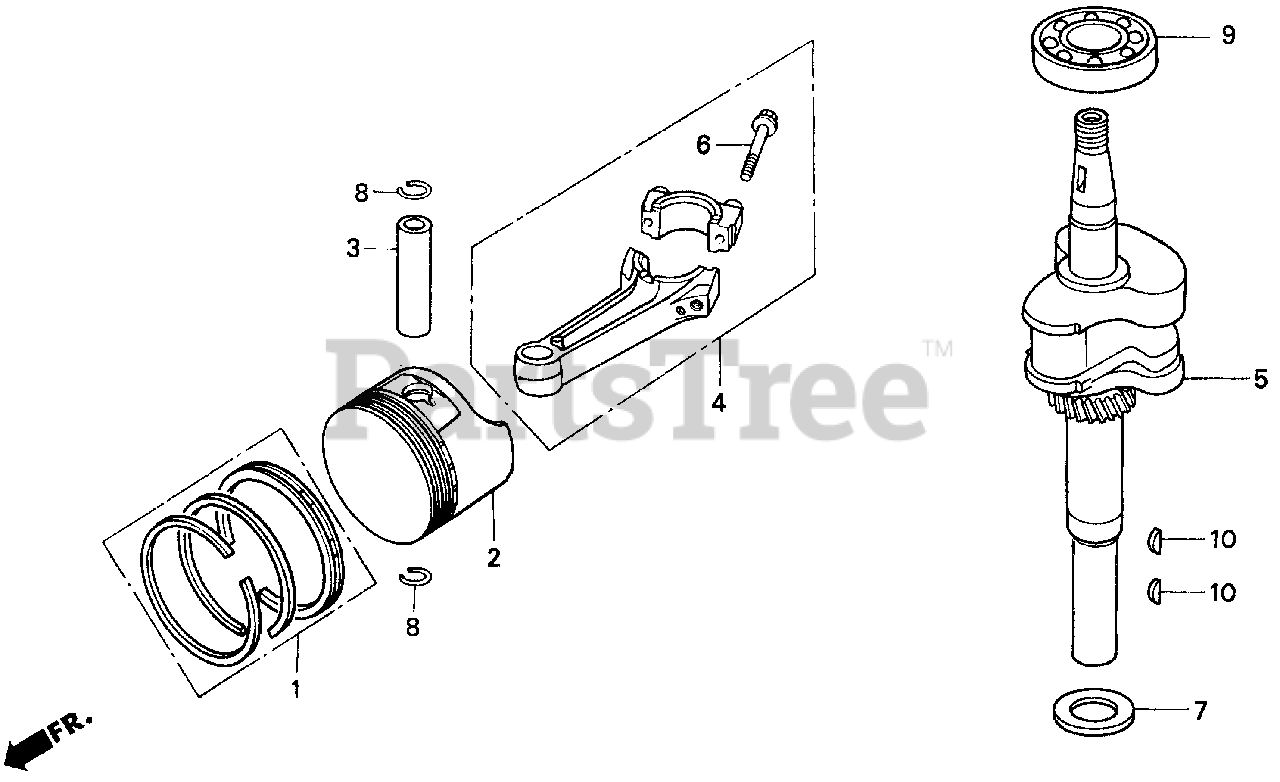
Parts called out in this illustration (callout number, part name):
1	RING SET, PISTON (STD)
1	RING SET, PISTON (OS 0.25)
1	RING SET, PISTON (OS 0.50)
1	RING SET, PISTON (0.75)
2	PISTON (STD)
2	PISTON (OS 0.25)
2	PISTON (OS 0.50)
2	PISTON (0.75)
3	PIN, PISTON
4	ROD ASSY., CONNECTING
5	CRANKSHAFT
6	BOLT, CONNECTING ROD
8	CLIP, PISTON PIN (13MM)
9	BEARING, RADIAL BALL (62/22)
10	KEY, WOODRUFF (16X15)
